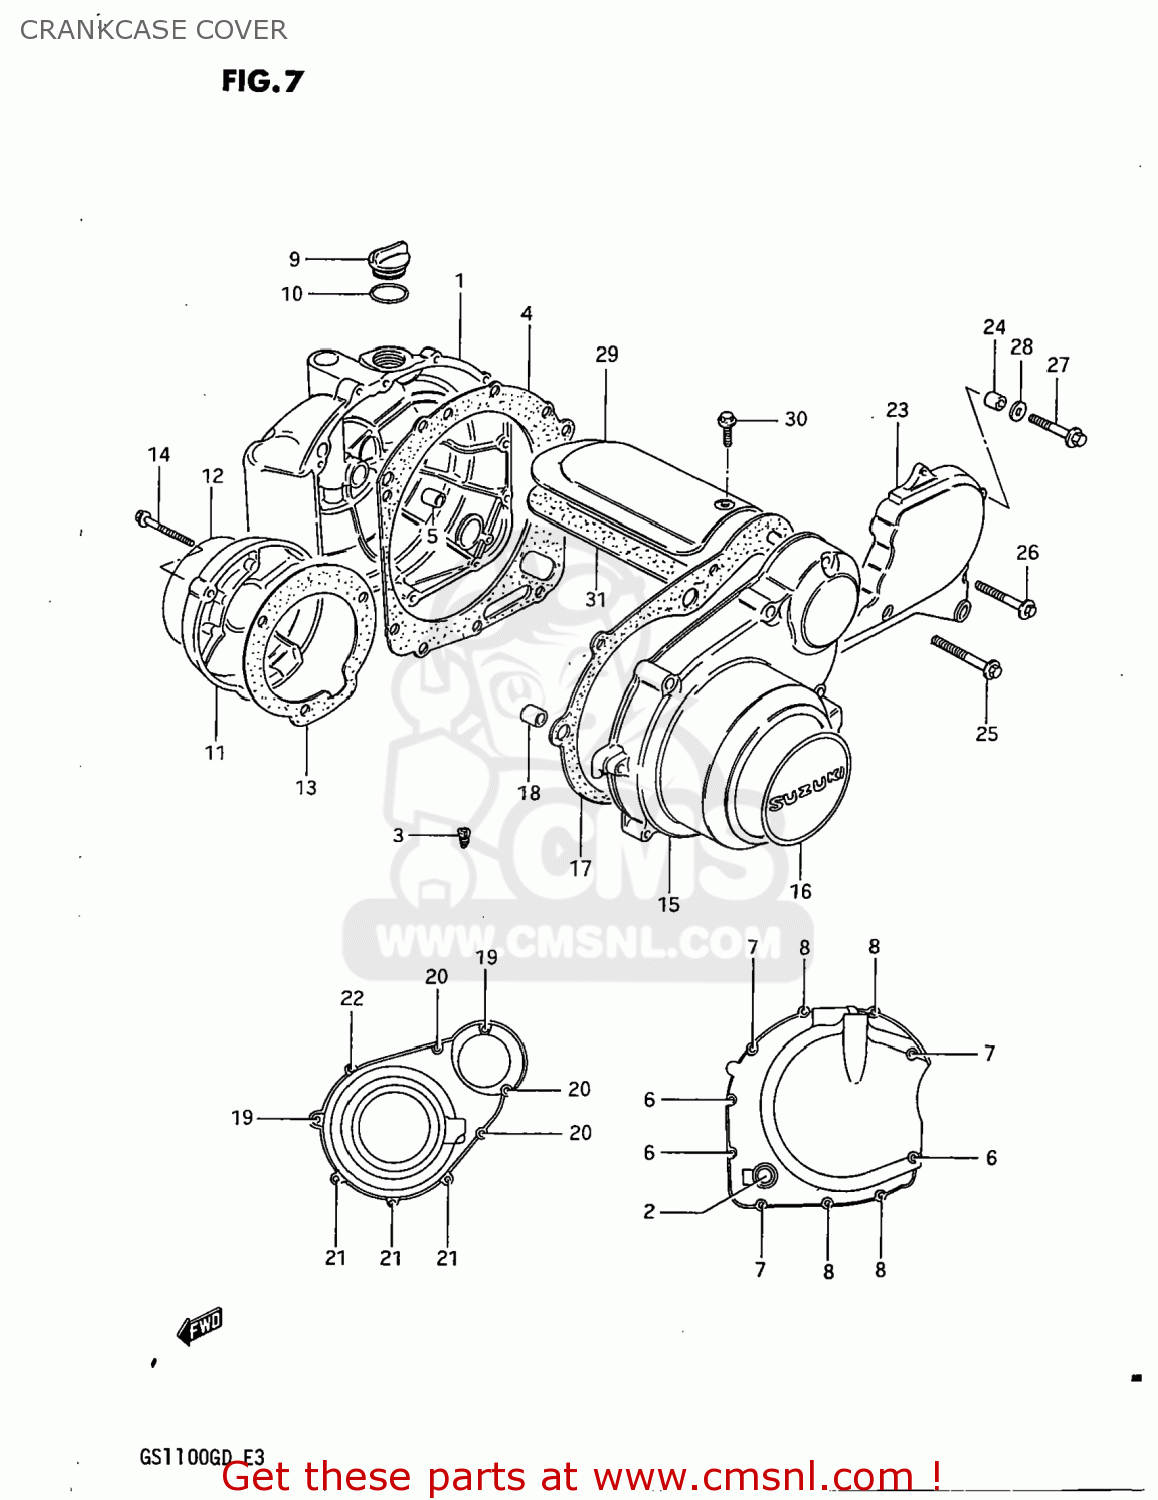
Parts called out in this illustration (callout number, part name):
1	COVER,CLUTCH
2	LENS,OIL LEVEL CHECK
3	JET
4	GASKET,MAGNETO COVER (N (MCA)
5	PIN
6	BOLT (6X35)
7	BOLT (6X30)
8	BOLT
9	CAP
10	O RING(D:2.2,ID:32)
11	COVER,CONTACT BREAKER
12	EMBLEM,CONTACT BREAKER COVER
13	GASKET,CONTACT BREAKER COVER (NAS)
14	BOLT (5X30)
15	COVER,MAGNETO
16	EMBLEM,MAGNETO COVER
17	GASKET,MAGNETO COVER (MCA)
18	PIN
19	BOLT
20	BOLT (6X40)
21	BOLT (6X35)
22	BOLT (6X30)
23	COVER,SECONDARY DRIVE
24	PIN
25	BOLT (6X30)
26	BOLT
27	BOLT (6X20)
28	WASHER
29	COVER,STARTER MOTOR
30	BOLT
31	GASKET,STARTER MOTOR COVER (MCA)
